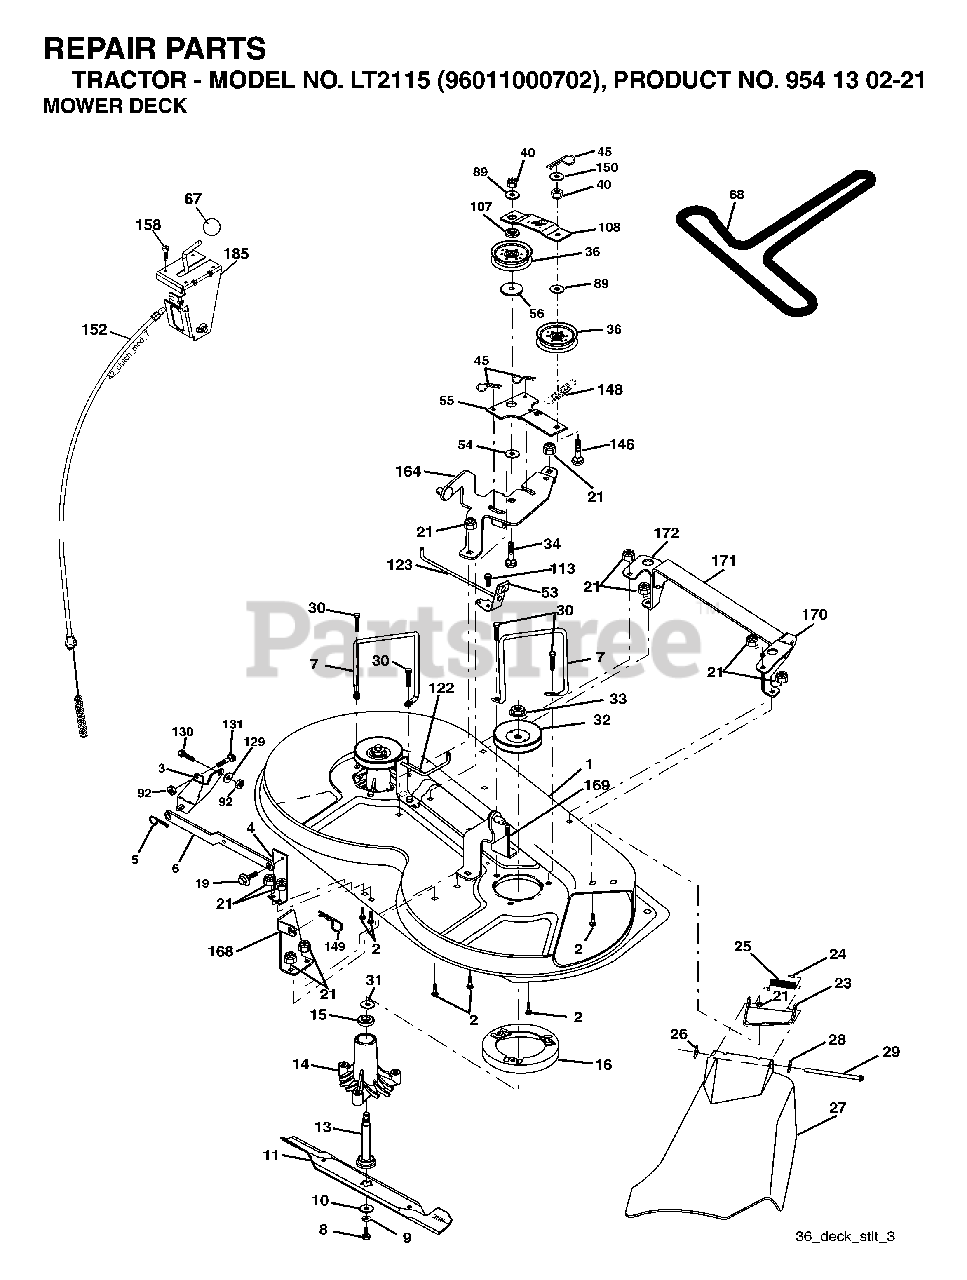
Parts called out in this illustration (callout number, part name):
2	BOLT
3	BRKT ASM SWAY BAR
5	RETAINER-SPRNG RB
6	BAR SWAY DECK
7	KEEPER LH
8	BLADE BOLT
9	LOCKWASHER
10	WASHER.BLADE
11	BLADE, HI-LIFT 36" PREMIUM
13	SHAFT ASM VENT
14	HSG MANDREL
16	STRIPPER, MWR ROUND
19	BOLT SHD 5/16-18
21	LOCKNUT
23	BRACKET ASM DEFLECTOR
24	CAP-SLEEVE LT
25	SPRING TORSION
26	NUT PUSH M
28	WASHER
29	HINGE ROD
30	SCREW, WASHER HEAD
31	WASHER.SPACER.MANDREL
32	PULLEY, MANDREL
33	NUT, FLG TOPLOCK 9/16"
34	BOLT
36	FLAT IDLER PULLEY
40	LOCKNUT
45	RETAINER M
53	BRAKE ASSEMBLY
55	IDLER ARM
56	SPACER.RETAINER.MOWER
67	KNOB T (3/8 HOLE)
68	V-BELT.MOWER.
89	WASHER
92	NUT
107	SPACER.IDLER.ARM
108	STIFFENER.IDLER.ARM
129	WASHER
131	BOLT D
146	BOLT, CARRIAGE IDLER
148	IDLER RETURN SPRING
149	SPRING.RETAINER.YELLOW.ZINC
150	WASHER LT
158	SCREW
171	BRACE
184	WASHER
185	HEAD ASM. CABLE CLUTCH
